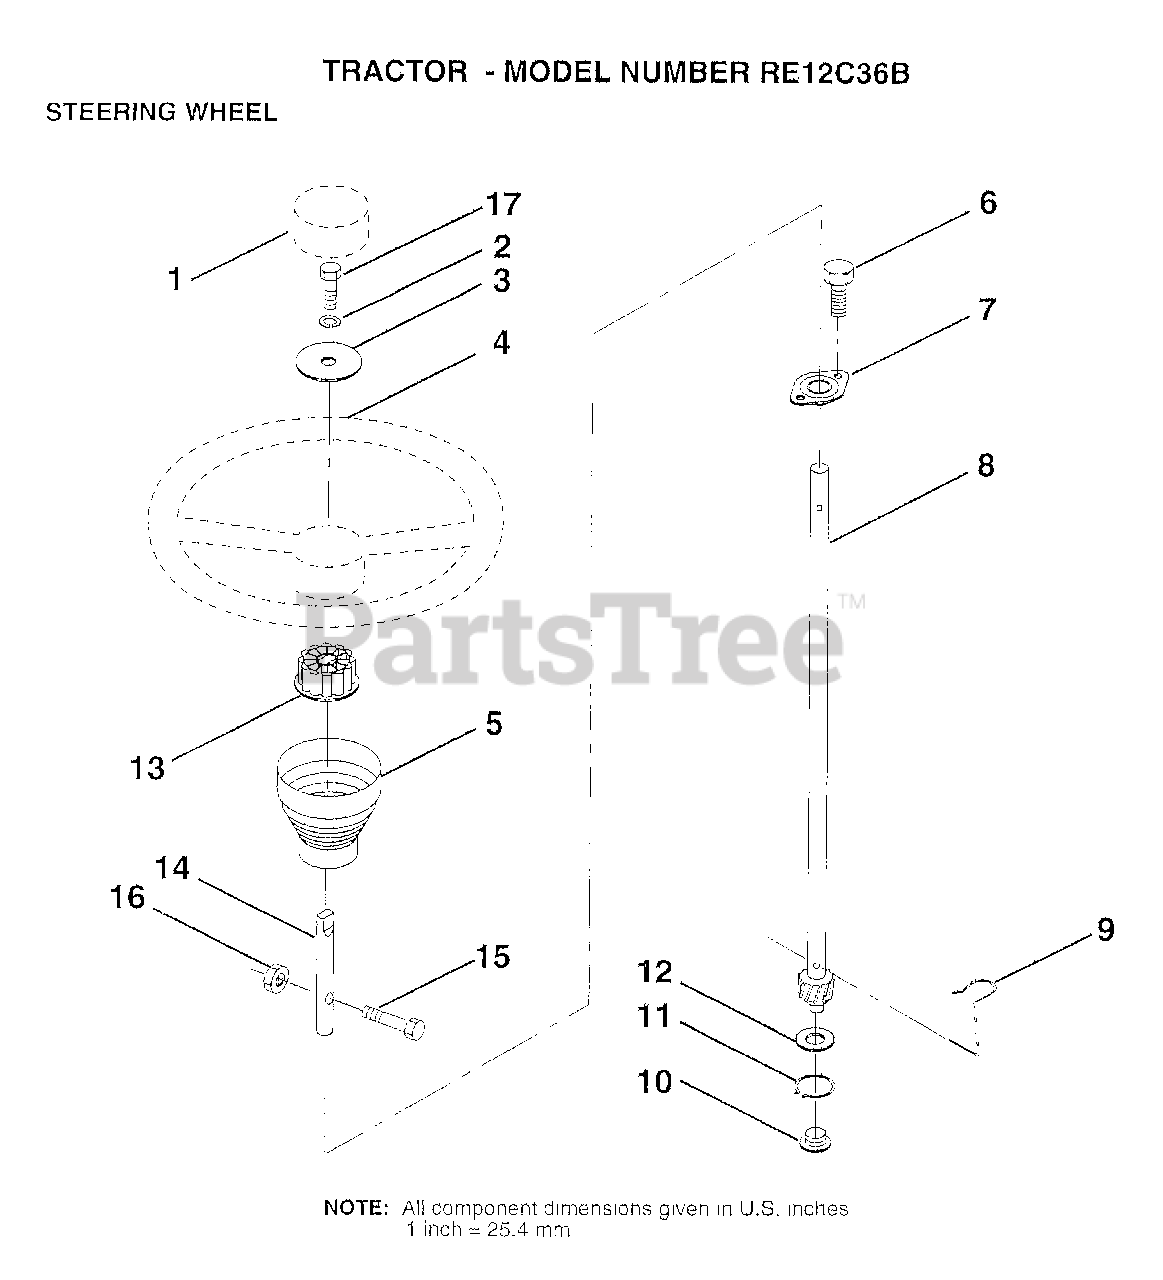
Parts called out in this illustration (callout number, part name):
1	ST WHL INSERT CAP
2	LOCKWASHER
3	WASHER T
5	SLEEVE STEERING
6	"SCREW-TT,10-32 FL"
7	BUSHING.STR.623
8	SHAFT.STEERING.LR
9	STEERING CLIP
10	BUSHING STEER LWR
11	RING
12	WASHER LT
13	ADAPTER LT
14	EXT SHAFT STEERIN
15	BOLT
16	NUT
17	BOLT
